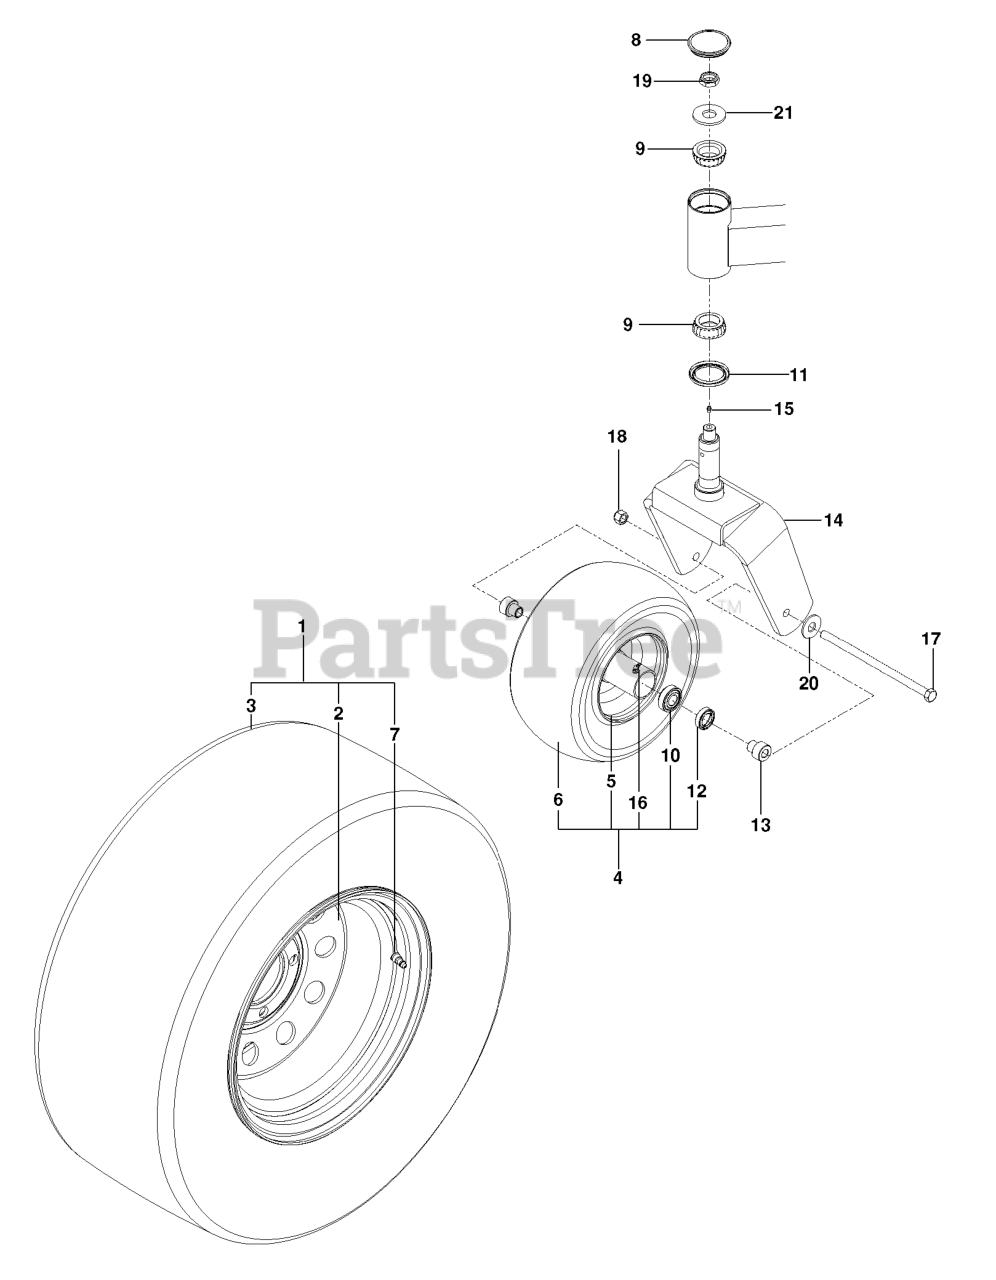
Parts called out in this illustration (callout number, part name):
1	WHEEL, DRIVE, 26 X 12
2	RIM, 12 X 8.5, CENTERED
3	TIRE, 26-12 X 12
4	TIRE, 13 X 6.5-6 NO FLAT
6	TIRE - SMOOTH 13X6.50-6
7	VALVE STEM TR-412
9	CONE, LM67048
10	TAPERED BEARING W/RACE
11	SEAL, BEARING
13	AXLE SPACER
14	FORK.CASTER.ORANGE
16	ZERK
17	HEX SCREW 1/2-13 X 9.5 GR5
18	NUT, 1/2-13 HEX FLG NYLOC ZD
19	NUT, 3/4-16 HEX THIN NYLOC ZD
20	WASHER 1/2" FLAT
21	WASHER, 3/4 HARDENED
